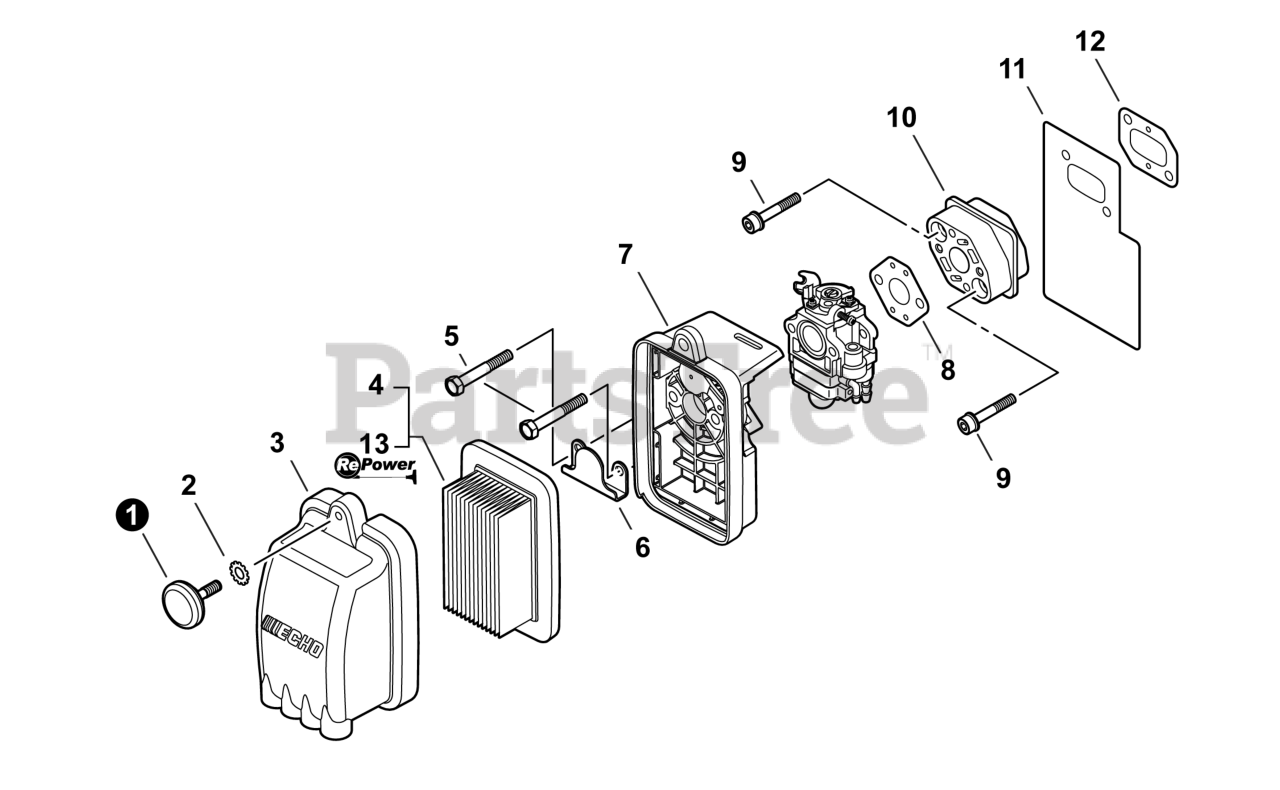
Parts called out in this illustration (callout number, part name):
1	THUMBSCREW
2	WASHER, LOCK
3	COVER, AIR FILTER
4	FILTER, AIR
5	BOLT 5×55
6	PLATE, PREVENT
7	CASE ASSY, AIR FILTER
8	GASKET, INTAKE
9	BOLT, FLANGE 5X25
10	INSULATOR, INTAKE
11	HEAT SHIELD, INTAKE
12	GASKET, INTAKE
13	TUNE-UP KIT - REPOWER
